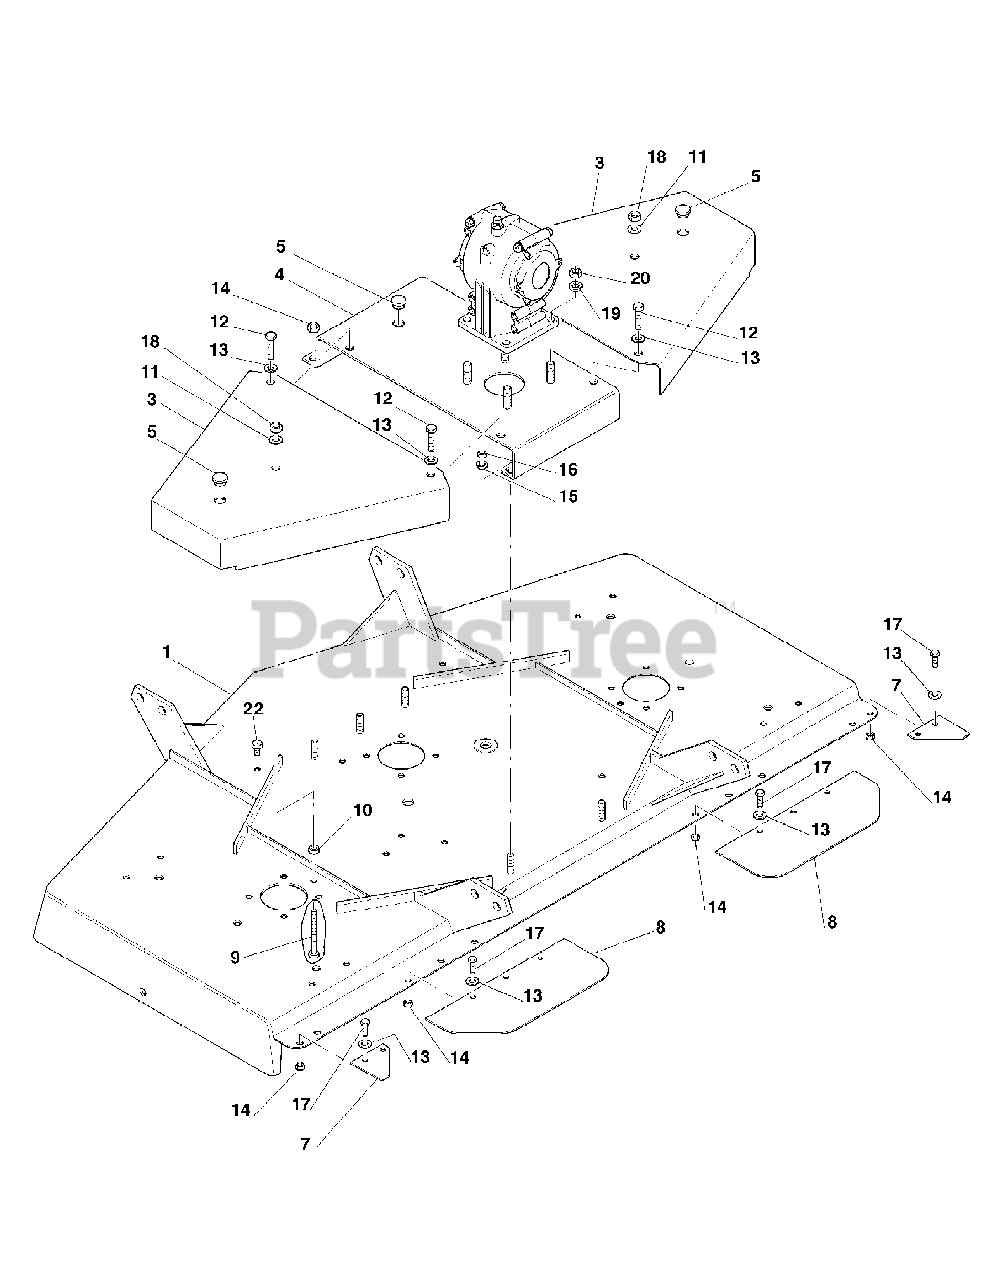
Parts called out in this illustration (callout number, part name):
1	Frame FM48 rear discharge
1	Frame FM60 rear discharge
1	Frame FM72 rear discharge
3	Belt shield FM48
3	Belt shield FM60
3	Belt shield FM72
4	Central plate FM48
4	Central plate FM60
4	Central plate FM72
5	Cap
7	Side rear protection FM60
7	Side rear protection FM72
8	Central rear protection FM48, FM60 & FM72
9	Bolt TE 10x110
10	Nut M10
11	Flat washer M10
12	Bolt TE 10x25
13	Flat washer M10
14	Nut M10
15	Spring washer M10
16	Nut M10
17	Bolt TE 10x20
18	Nut M10
19	Spring washer M12
20	Nut M12
